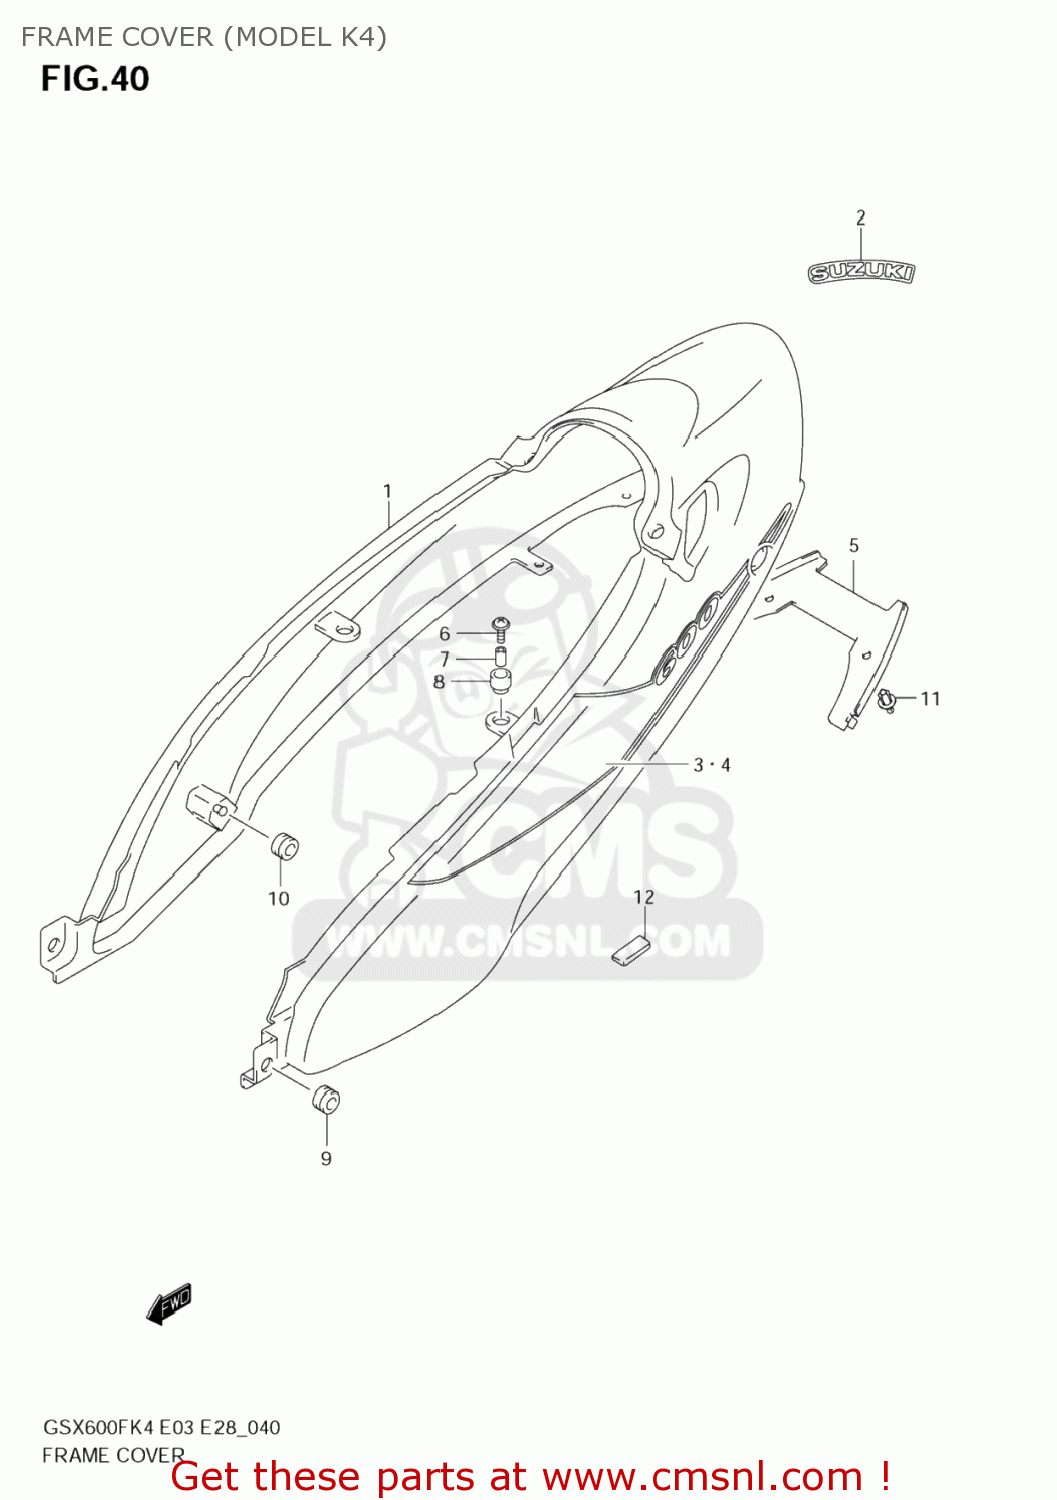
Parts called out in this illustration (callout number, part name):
1	COVER,FRAME(BLACK)
2	EMBLEM,SUZUKI
3	TAPE,FRAME COVER STRIPE,R
4	TAPE,FRAME COVER STRIPE,L
5	COVER,FRAME LWR
6	SCREW(6X20)
7	SPACER(6.5X10X9.4)
8	CUSHION
9	CUSHION
10	CUSHION
11	CLIP(BLACK)
12	CUSHION
